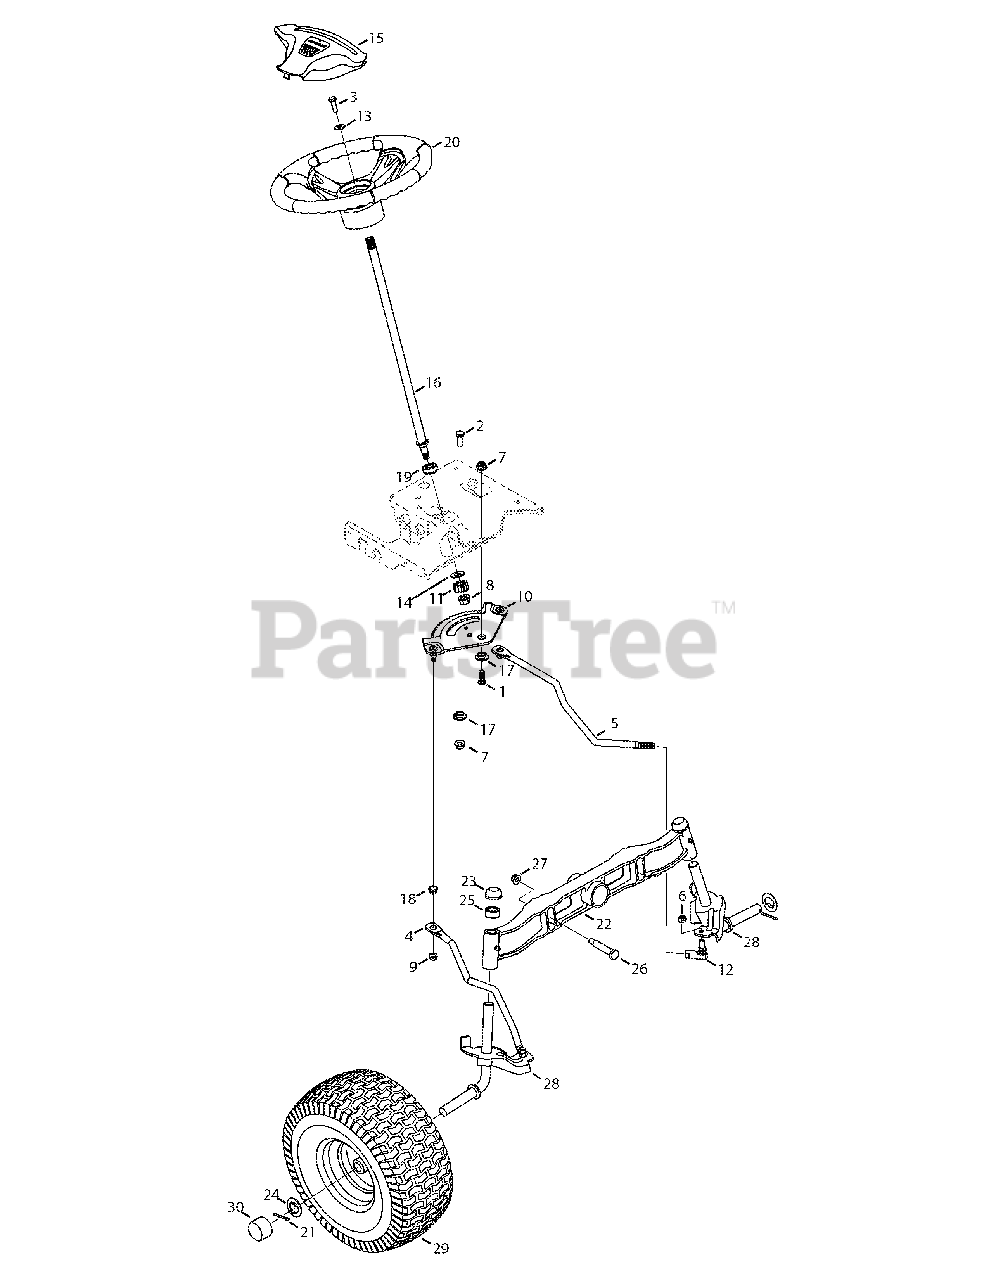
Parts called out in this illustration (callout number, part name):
1	Hex Cap Screw, 3/8-16, 1.00
2	Hex Cap Screw, 3/8-16, 1.00, Gr5, Std
3	Self-tapping Screw, 5/16-18 x .75
4	Link, Drag, RH
5	Link, Drag, LH
6	Nut, Hex, 3/8-24, Gr5
7	Nut, Nylon Lock, 3/8-16
8	Nut, Flange Lock, 7/16-20
9	Nut, Flange Lock, 5/16-18
10	Gear, Steering, 11/90 Ratio
11	Gear, Pinion, Steering
12	Ball Joint, 7/16-20
13	Washer, Flat, .406 x .875 x .105
14	Washer, Flat, .510 x 1.120 x .060
15	Cover, Steering Wheel
16	Shaft, Steering, .625 OD x 25.00 Lg
17	Spacer, Shoulder, 1.00 x .38 x .38
18	Bushing, Plastic, .380 ID
19	Bearing, Hex Flange, 5/8
20	Wheel, Steering, Three Spoke
21	Pin, Cotter, 5/32, 1.25
22	Axle, Pivot Bar, Cast
23	Push Cap, .75
24	Washer, Flat, .781 x 1.590
25	Spacer, .71 x .125 x .56
26	Screw, Shoulder, .500 x 2.23, 3/8-16
27	Nut, Jam, 3/8-16, Grf.
28	Axle Ass’y, LH .750 Dia.
28	Axle Ass’y, RH .750 Dia.
29	Wheel Assembly
